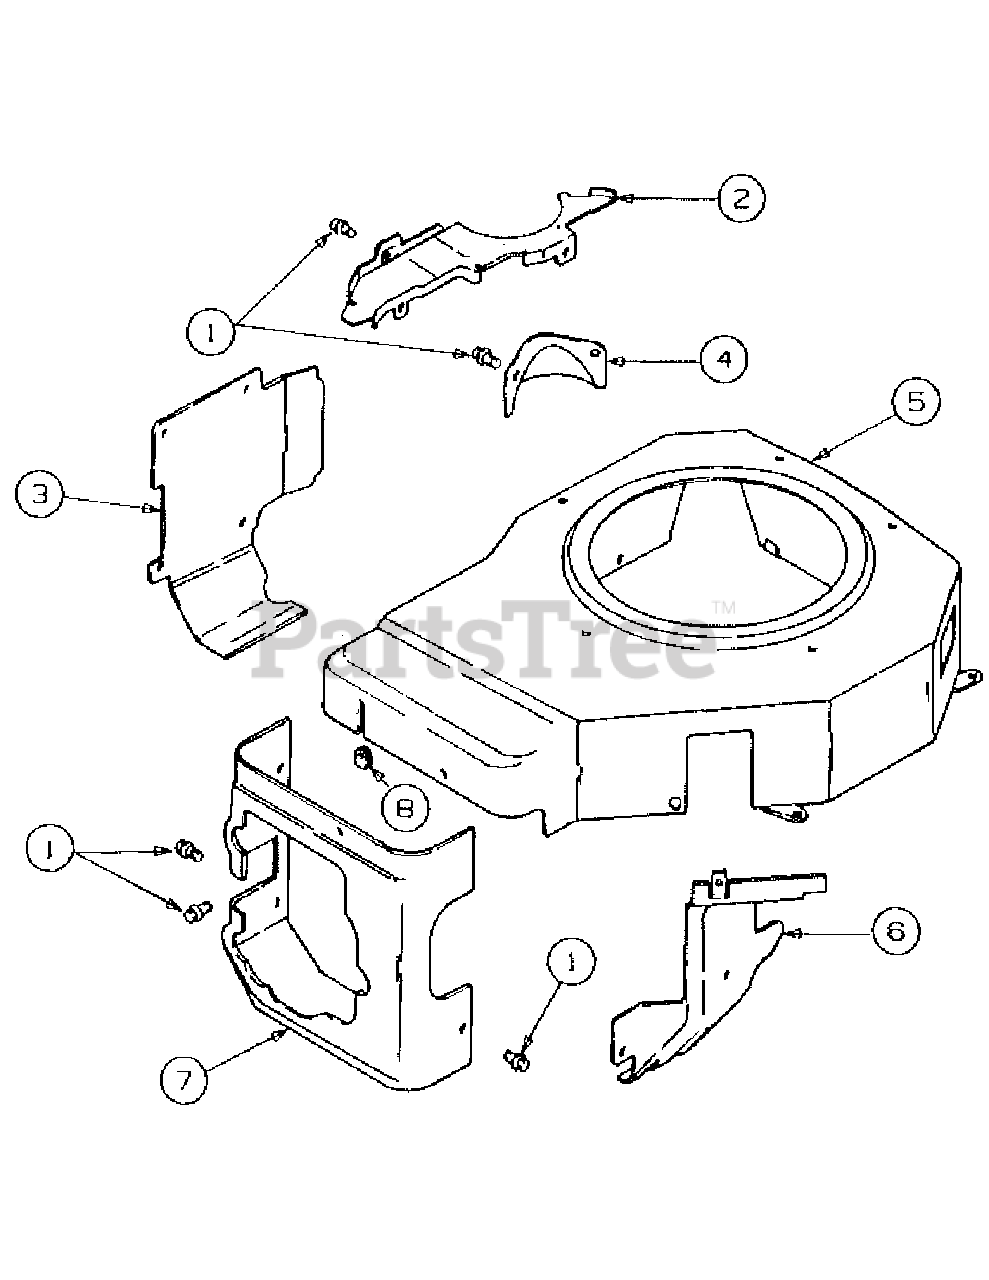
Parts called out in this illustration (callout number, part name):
1	Screw, Mounting, M5 x 0.8 x 10
2	Plate, Blower Housing
3	Baffle, Cylinder Barrel
4	Cover, Starter
5	Housing, Blower
6	Baffle, Carburetor
7	Baffle Cylinder Head
8	Grommet, Blower Housing
